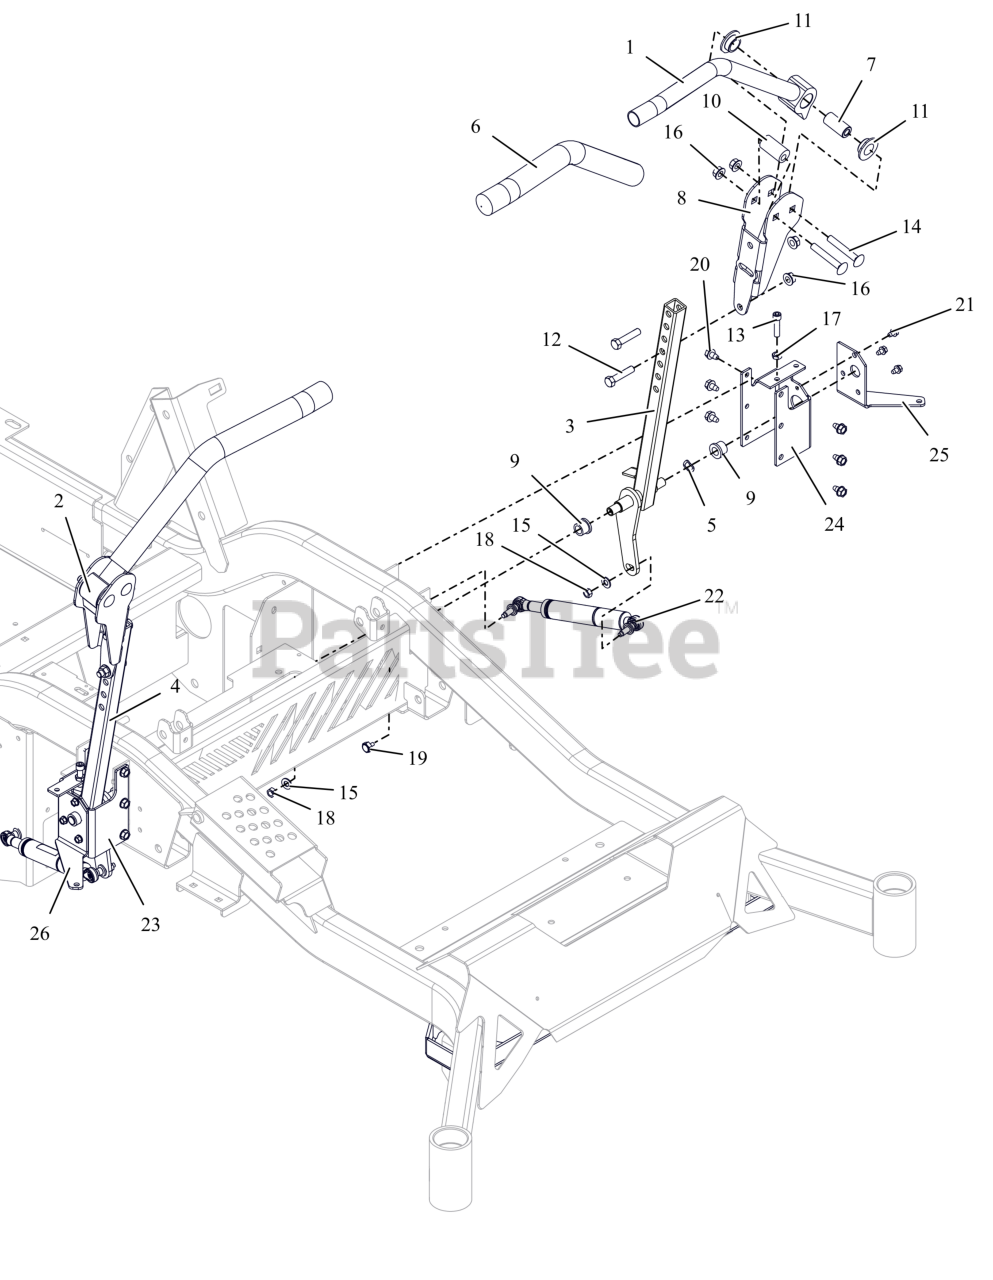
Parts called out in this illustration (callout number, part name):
1	WLDMT, CONTROL HANDLE (RED)
2	WLDMT, CONTROL HANDLE (RED)
3	WLDMT, STEERING -LH (RED)
4	WLDMT, STEERING RH (RED)
5	WAVE WASHER .531X.781X.125FH
6	GRIP, HANDLEBAR
7	SPACER, STEERING ARM
8	BRKT, ADJ UPPER CONTROL ARM (RED)
9	BSHG, FLG .516X.750X.625X.937
10	BSHG, ECCENTRIC.406X.875X1.625
11	BSHG, FLANGED .762 X 1.48 X .44 IGLIDER
12	BLT, HEX .38-16X1.75 G5 ZCC
13	SCR, SKH .312-18X1.25 GR8 ZC120
14	BLT, RHSSN.38-16X2.50 G5 ZCC
15	WSHR, HRDN 0.344X0.688X0.065
16	NUT-LK-CTR-FLG .375-16 GF ZCC
17	NUT-JAM .312-18 G2 ZCC
18	NUT-HEX-JAM-CTR LK M8X1.25 ZCC
19	BOLT, MAGNETIC STEERING SENSOR
20	SCR,TAP .312-18X.50 HWH TR ZCC
21	SCR,TAP .25-20X.375 HWH TR ZCC
22	DAMPER, NEUTRALIZING
23	BRKT, STEERING ARM MOUNTING-RH (RED)
24	BRKT, STEERING MOUNTING -LH (RED)
25	BRKT, FRONT FENDER MOUNT-LH (BLACK)
26	BRKT, FRONT FENDER MOUNT-RH (BLACK)
